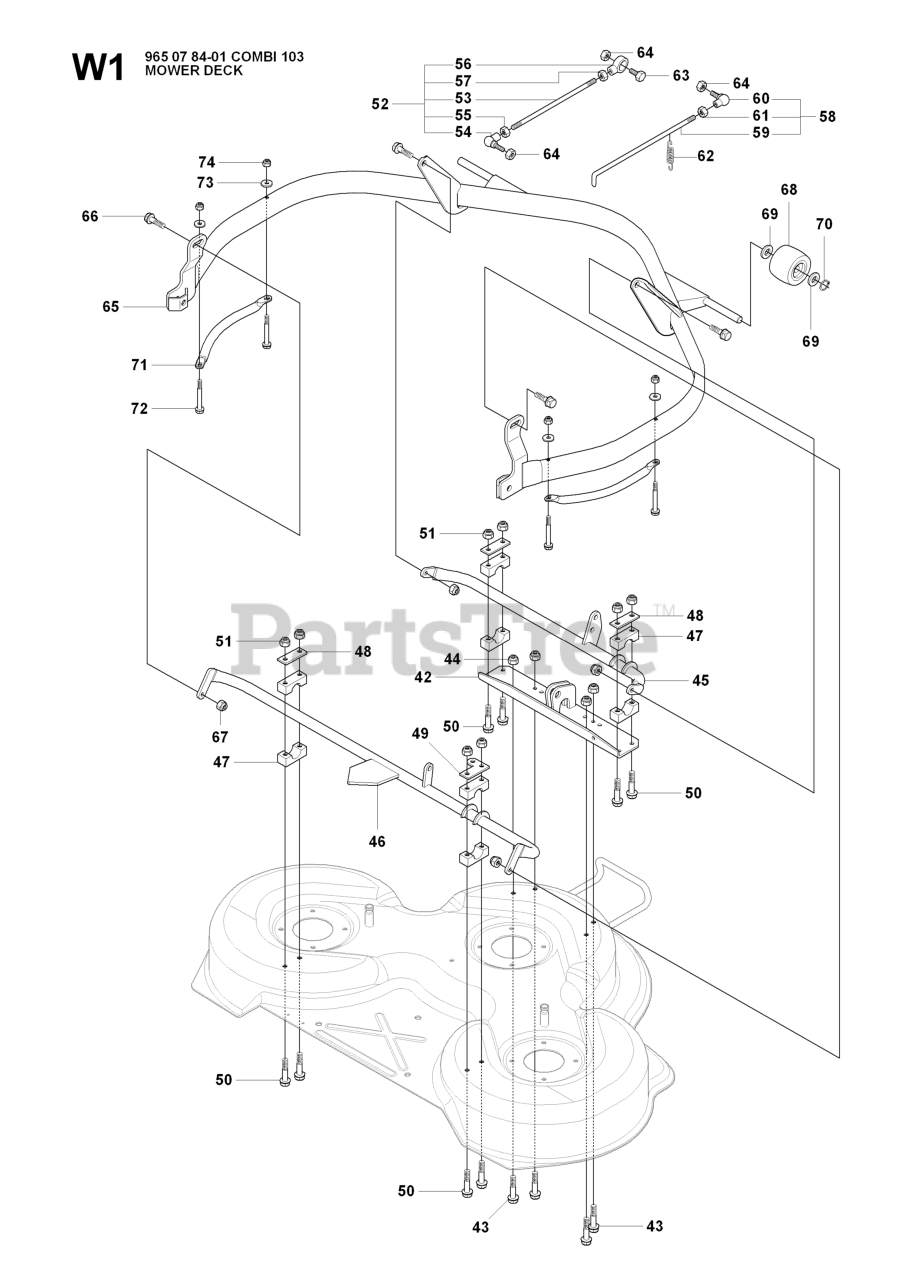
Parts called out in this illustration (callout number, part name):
44	LOCKNUT M8
51	LOCKNUT M8
52	PARALLEL RODY ASSY
57	NUT
58	CLUTCH ROD ASSY
64	NUT
65	PROTECTIVE TUBING
67	LOCKNUT M8
68	DECK ROLLER, FRONT
70	RETAINING RING SGA 15
73	WASHER
74	LOCKNUT M6
